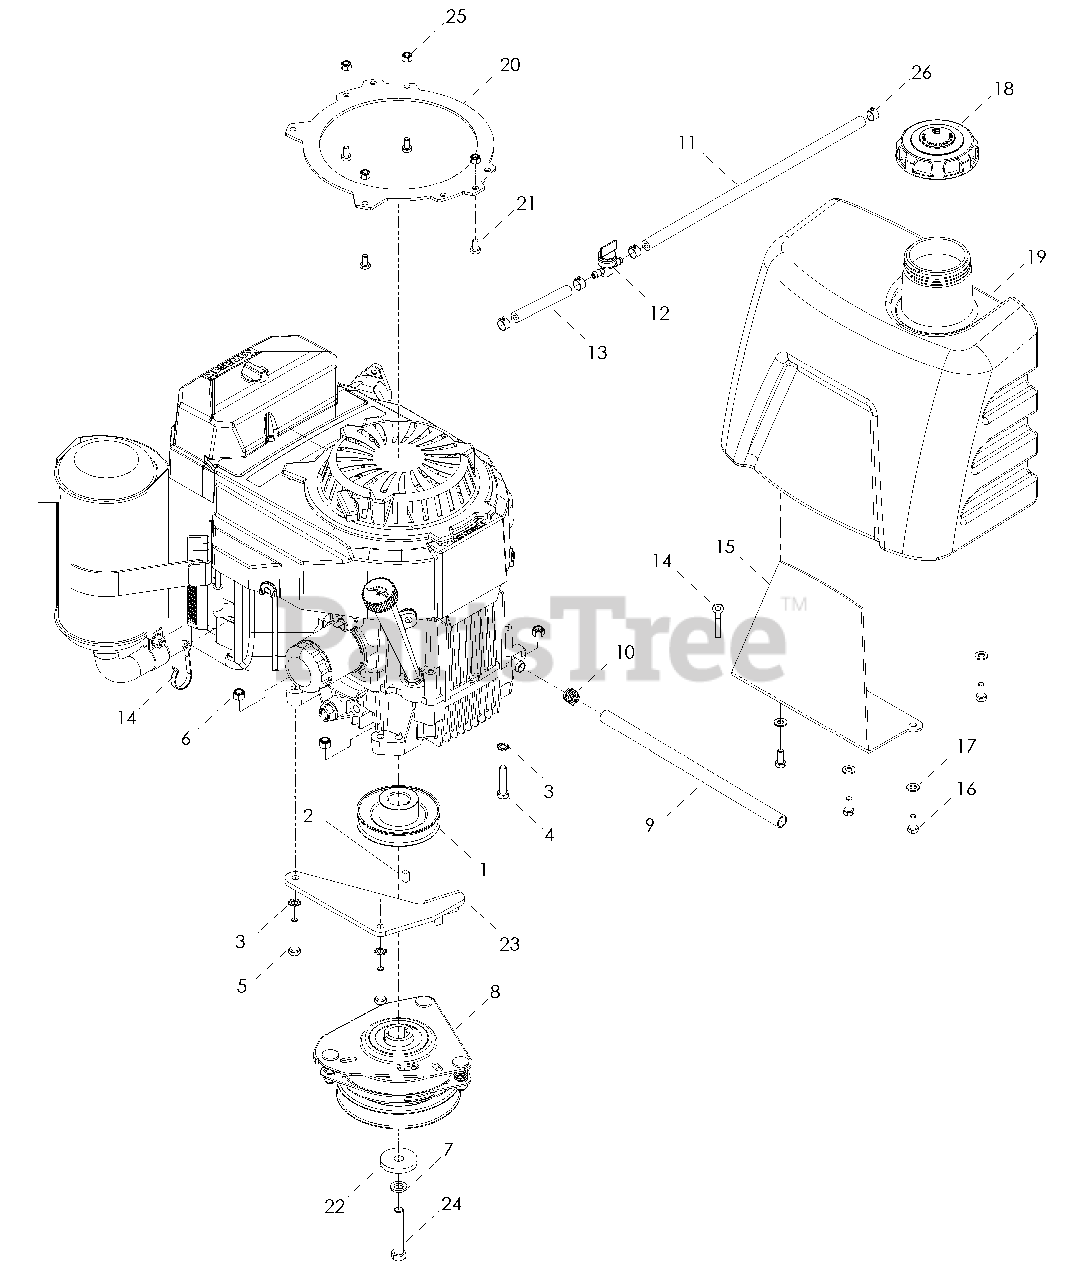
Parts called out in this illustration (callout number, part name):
2	KEY 1/4" SQ x 1/2"
3	LOCK WASHER 5/16 STAR
4	HCS 5/16-18 x 1 1/2
5	HCS 5/16-18 x 1 3/4
6	NUT 5/16-18 HEX NYLOC
7	LOCKWASHER 7/16 SLOT
8	CLUTCH 90 FT/LB
9	HOSE, OIL DRAIN
10	CLAMP, HOSE
11	FUEL LINE, 12"
12	FUEL VALVE
13	FUEL LINE, 2 1/2"
16	HCS 5/16-18 x 3/4
17	WASHER 5/16 SAE FLAT
18	CAP, FUEL TANK
19	TANK, FUEL
20	ADAPTER, RECOIL
21	HCS 1/4-20 x 1/2
22	WASHER, HEAVY
23	CLUTCH STOP
24	HCS 7/16-20 x 2 1/2
25	NUT 1/4-20 HEX NYLOC
